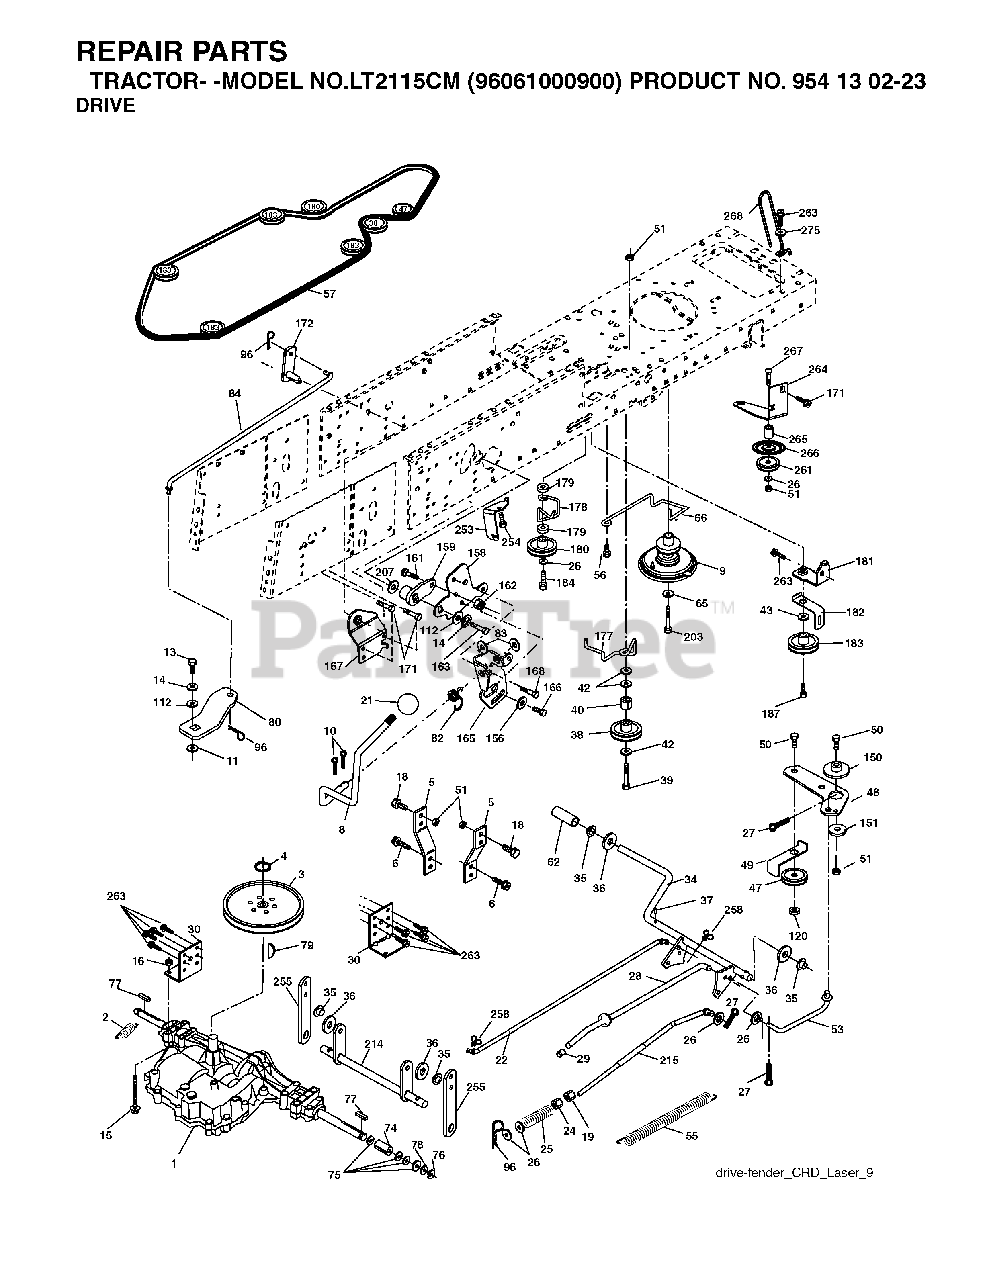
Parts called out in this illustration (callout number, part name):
2	SPRING,BRAKE RETURN
4	RETAINING RING LT
5	STRAP TORQUE
6	SCREW 5/16"
8	ROD SHIFT
10	PIN COTTER
11	WASH-SHFT PLT LT
13	BOLT 1/4-28X3/4
14	LOCKWASHER
15	BOLT HEX 5/16-18 GR 5
16	NUT.71038.31-18.HEX.NYLOCK
19	NUT
21	KNOB.DUCKHEAD.1/2
24	NUT
25	SPRING ROD LT
27	COTTER PIN
28	ROD, PARKING BRAKE
29	PLUNGER CAP
30	BRKT, MOUNT TRNSAXLE
34	SHAFT, FOOT PEDAL
35	BEARING.NYLON
36	WASHER LT
37	DRIVE PIN
38	PULLEY.FLAT
42	WASHER
47	IDLER PULLEY
48	BELLCRANK, CLUTCH
49	RETAIN BELT
50	BOLT.3/8-16X1.50
51	LOCKNUT
53	LINK, CLUTCH LT
55	SPRING, RETURN LT
56	SCREW.3/8-16
57	V-BELT.KEV.111"
62	PEDAL COVER T
65	LOCKWASHER
66	KEEPER BELT ENGINE
74	SPACER AXLE
76	E-RING LT
77	SQUARE KEY
80	ARM SHIFT
82	SHIFT SPRING
83	WASHER
96	RETAINER M
112	WASHER LT
120	NUT LOCK FLG 3/8-16 UNC
150	BUSHING.BELLCRANK.GRD.DR
151	WASHER 12/32X2X10GA
156	WASHER.SRRTD.5/16
158	BRACKET
159	HUB.SHIFT
161	BOLT
162	NUT.CROWNLOCK.1/4
165	RP BRACKET
167	BRACKET
168	BOLT.SHOULDER.5/16-18X
180	PULLEY.FLAT.IDLER
184	SCREW.HXWSH.3/8
187	BOLT.5/16-18X1.25
207	WASHER NYL
254	SCREW 3/8-16X1
258	CLIP RETAINER
261	FLAT IDLER PULLEY
263	SCREW, 3/8-16X3/4
265	SPACER IDLER
275	WASHER
